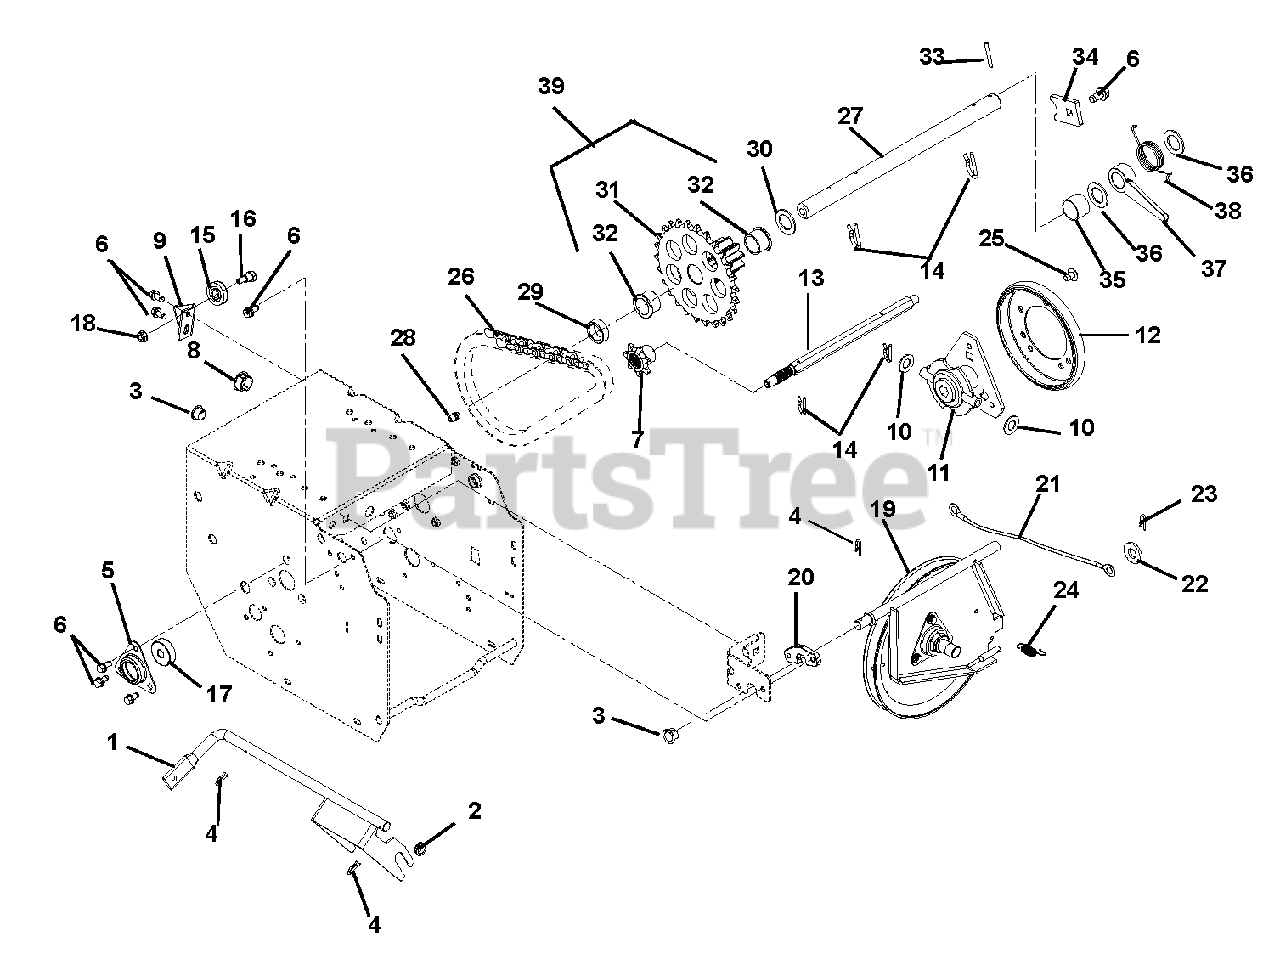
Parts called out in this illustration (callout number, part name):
1	WELDMENT, SHIFT FORK
2	BUSHING, POLYLINER-.50 SNAPIN
3	BUSHING, POLYLINER-.50 SPLIT
4	CLIP, SPRING
5	FLANGE, BEARING
6	SCR-TAP .25-20X.50 HWH TR YWZ
7	SPROCKET, PINION 7T W/SPLINE
8	PLUG, HOLE - .875" NYLON
9	BRACKET, CABLE PULLEY
10	WSHR-FL-STL .505X1.00X.062YWZC
11	CARRIER, DRIVE DISK
12	FRICTION, DISC
13	SHAFT, HEX W/SPLINE
14	PIN, SPRING CLIP
15	PULLEY, CABLE
16	BOLT, SHLDR-.375X.375X.25-20
17	BRG-BALL .437X1.375X.437
18	@NUT-LK-TOP-FLG .25-20 YWZC
19	PLATE, SWING - ASSEMBLY
20	SPACER, SWING GATE
21	CABLE, TRACTION - TRACTOR
22	@WSHR-FL-STL.344X.688X.065YWZC
23	PIN-HAIR INT .08X.18X1.18 YWZC
24	SPRING, EXT. .043X.438X1.64
25	SCR-TAP SERRDHDTX .31-18X.50BP
26	CHAIN - #41, 32 PITCHES
27	SHAFT, PINION
28	ZERK,FITTING .25X.125 DRIVE IN
29	BSHG-SLV, .635X.880X.305
30	WSHR-FL-STL .630X1.005X.062 YZ
31	PINION & SPROCKET
32	BSHG-FLG .625X.750X.500X.875
33	@PIN-GRV .125X1.00 TP E ALLOY
34	TAB, ANTI ROTATION
35	SPACER, .635X.880X.611
36	WSHR-FL-STL .630X1.005X.062 YZ
37	LEVER, LOCK ARM
38	SPRING, TORSION
39	PINION & SPROCKET W/BUSHINGS
